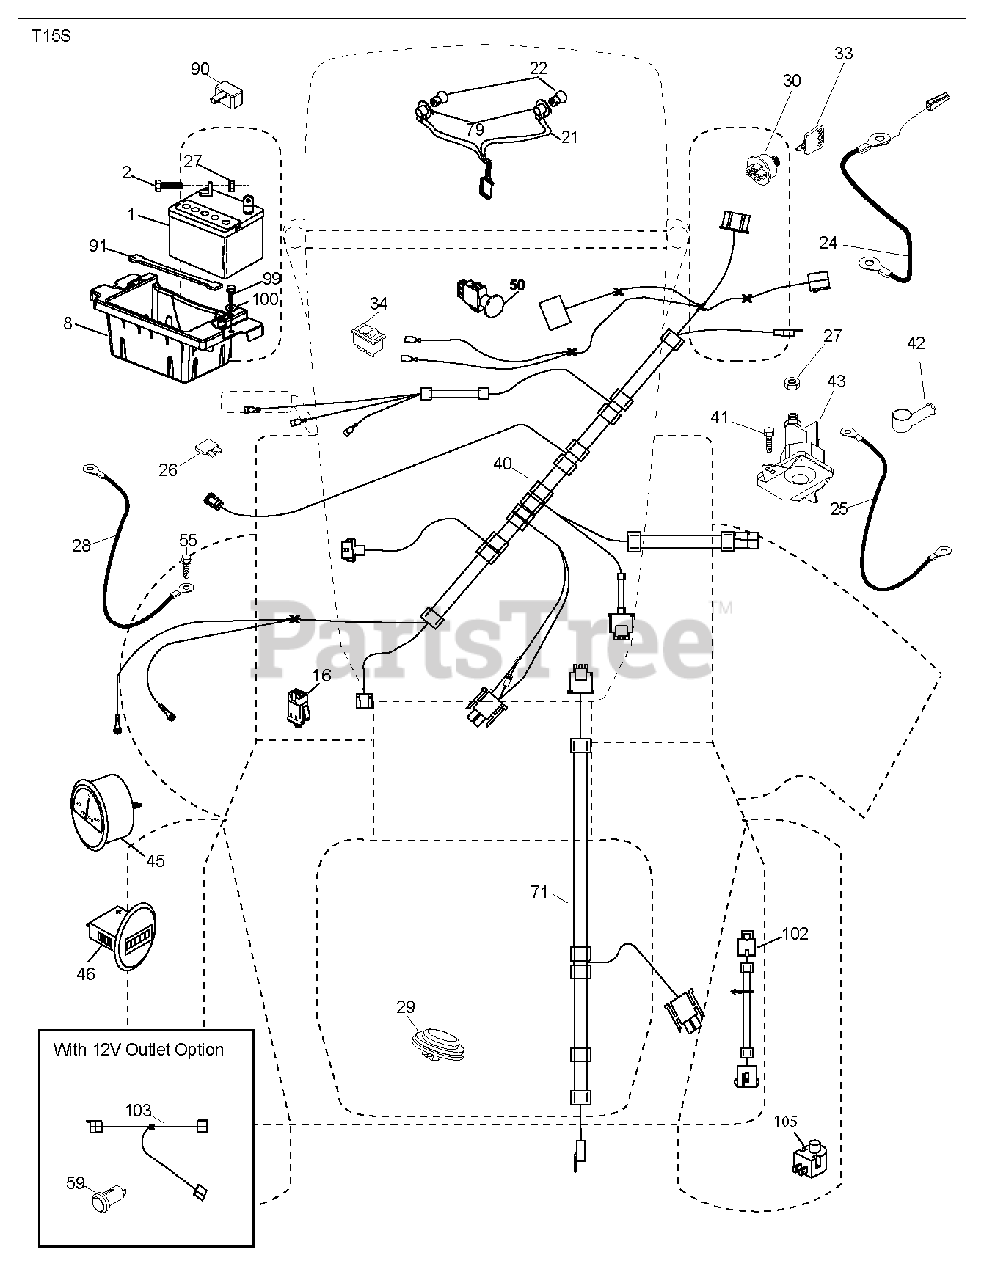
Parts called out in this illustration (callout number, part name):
2	BOLT LT
8	BOX, BATTERY MOUNT
16	SWITCH INTERLOOK PUSH-IN
21	HARNESS SOCKET LIGHT
22	LIGHTBULB
24	CABLE.BTRY.PSWRE.DSH.S
25	CABLE.STARTER.6G.BL/RED.17.5
26	FUSE 20AMP
28	CABLE GROUND 6 GA 21" 90T BLK
29	SWITCH.SEAT.DELTA.OPC.
30	IGNITION SWITCH
33	KEY/CHAIN.BLISTER.PACK.GEN.USA
34	SWITCH LT
40	HARNESS IGN. DASH
43	SOLENOID.W/BRASS.PLUNG
45	AMMETER.ROUND.SNAPIN
46	HOURMETER.ROUND.SNAPIN
50	PTO SWITCH
71	HARNESS-CHASSIS SUB
79	BULB HOLDER ASM.
91	STRAP, BATTERY MOUNT
99	SCREW HEXWSHR 1/4-20X3/4
102	HARNESS PIGTAIL PCH TEX ROS
105	REVERSE SWITCH
